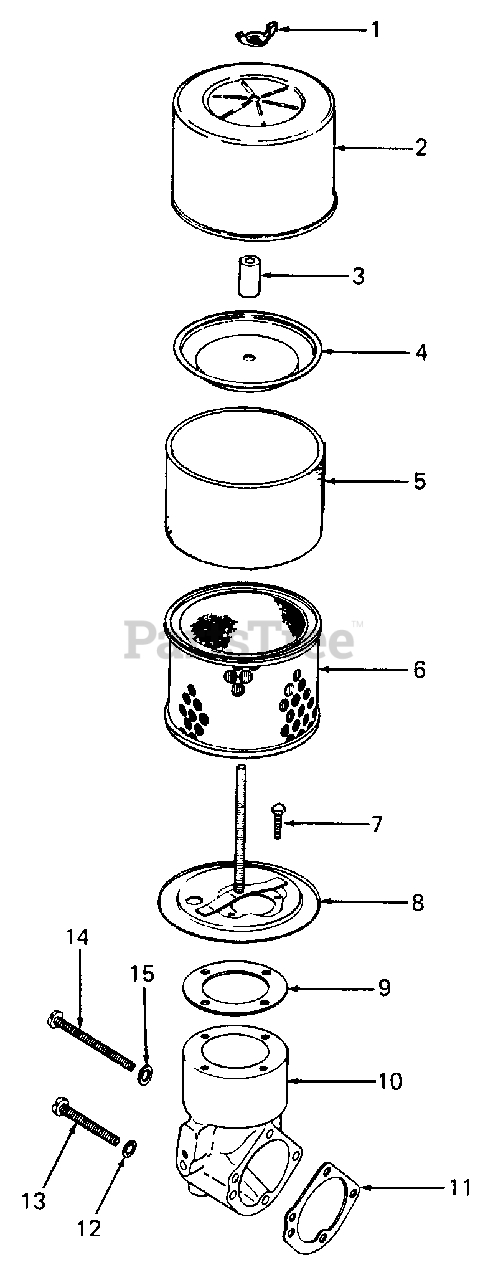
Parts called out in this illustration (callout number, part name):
1	Nut, Wing, 1/4-20
2	Cover, Air Cleaner
3	Seal, Element Cover
4	Cover, Air Cleaner Element
5	Precleaner
6	Element
7	Screw, Sltd Hex Wash Hd, #10-32 X 9/16 Lg
8	Base, Air Cleaner
9	Gasket, Air Cleaner
10	Elbow, Air Intake
11	Gasket, Air Intake Elbow
12	Washer, I.T. #10
13	Screw, Sltd Pan Hd, #10-32 X 1.5 Lg
14	Screw, Sltd Pan Hd, #10-32 X 2.25 Lg
15	Washer, Plain, #10
